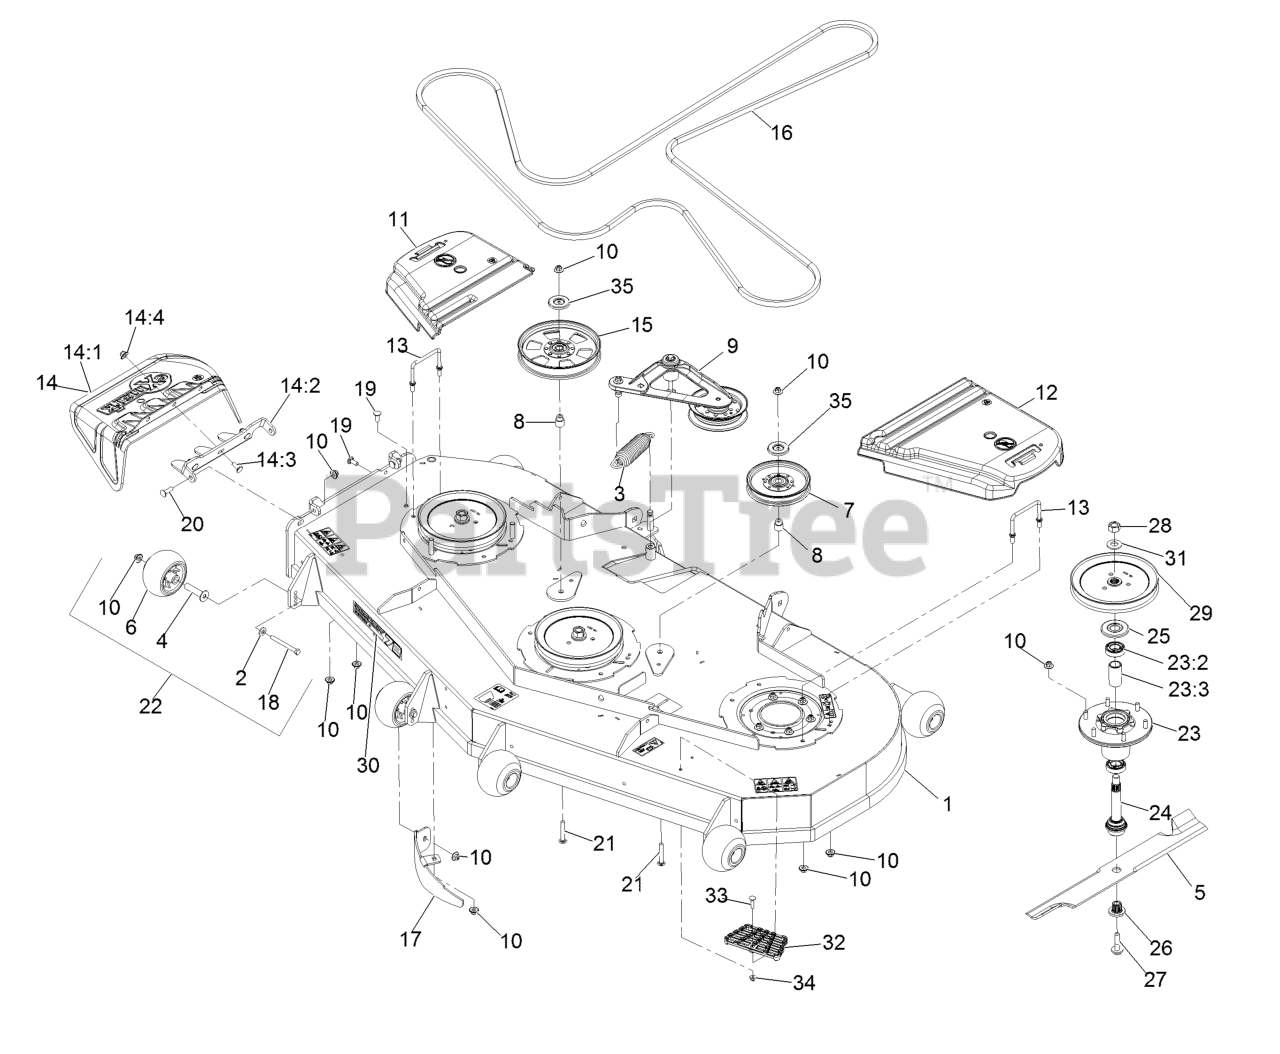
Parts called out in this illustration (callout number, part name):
1	ASM,Deck W/Decals 724
2	Washer-Spring Disc 3/8
3	Spring-Extension
4	Axle, Roller
5	Blade, Solid (72")
5	Blade, Low Lift (72")
5	Blade, Mulching
5	Blade, Notched (72")
5	Blade-Extreme 2, 24.50"
6	Roller-Anti-Scalp
7	Idler-Pulley
8	Bushing, Idler
9	Deck Idler ASM
10	Nut-Nyloc 3/8-16 Flg
11	Cover-Belt, RH
12	Cover-Belt, LH
13	Wireform-Cover
14	ASM,Discharge Chute
14:1	Chute, Discharge
14:2	Bracket,Discharge Chute
14:3	Bolt-Carriage 3/8-16 X 1
14:4	Nut-Nyloc 3/8-16 Flg
15	Pulley-Idler, Flat
16	Belt-V
17	Baffle-Dogleg, Lz72
18	Screw-HH 3/8-16 X 3 3/4 GR 8
19	Bolt-Carriage 3/8-16 X 1
20	Bolt-Carriage 3/8-16 X 1 1/4
21	Bolt-Carriage 3/8-16 X 2 1/2
22	Kit, Anti-Scalp Roller
23	ASM-Cutter Hsg With Bearings
23:2	Bearing-Ball
23:3	Spacer-Bearing
24	ASM-Spindle And Seal
25	Guard,Bearing Top .989
26	Bushing, Splined
27	Screw-Sems 1/2-20 X 2.19
28	Nut-Hex
29	Sheave,Blade Drive 8.74
30	Decal, 724
31	Washer-Spring Disc 3/4
32	Step-Deck
33	Screw-CARR
34	Nut-HF, NI
35	Shield-Dust
